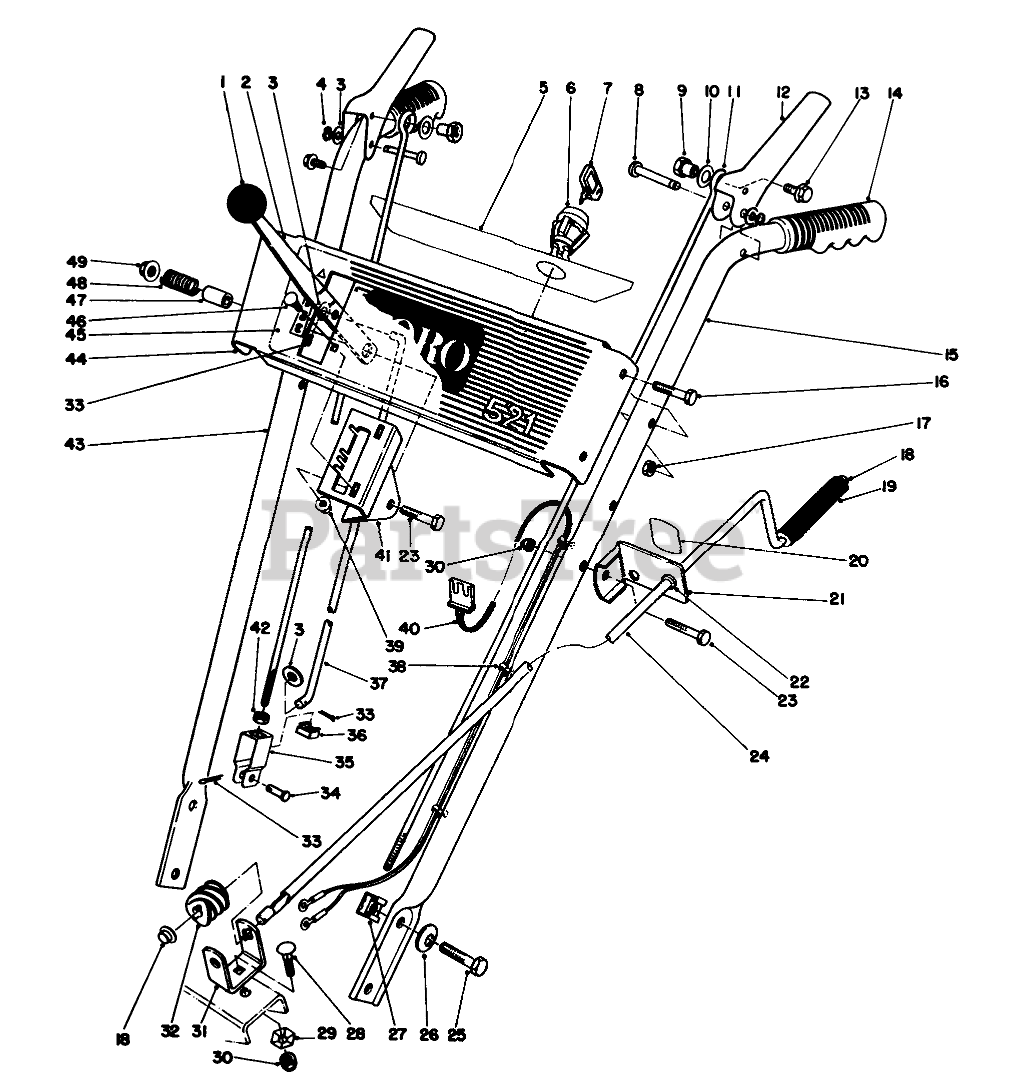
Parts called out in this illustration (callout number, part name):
2	SPEED SELECTOR B
3	WASHER-PLAIN
4	RING-CLIP
5	DECAL - ESCUTCHEON BACK
6	SWITCH
7	KEY-IGNITION
8	PIN-LEVER, CONTROL
9	POST-MOUNTING, LINKAGE
10	WASHER-FLAT
11	LINK-UPPER
12	HANDLE-CONTROL
13	SCREW-HHF
14	Grip
15	LEFT HANDLE
16	SCREW-HH
17	NUT-LOCK, NI
18	RETAINER-PUSH ON
19	Grip-Rod
20	DECAL-CHUTE DIRECTION
21	BRACKET W/DECAL
22	Bushing
23	SCREW-HH
24	ROD-CONTROL, CHUTE
25	SCREW-HH
26	WASHER-BELLEVILLE
28	BOLT-CARR
29	WASHER-LOCK
30	NUT-LOCK, NI
31	BRACKET-WORM
32	GEAR-WORM, CHUTE
33	PIN-COTTER
34	PIN-CLEVIS
35	CLEVIS
36	NUT-RETAINED
37	ROD-SELECTOR, SPEED
38	Mount-Wire
39	NUT-HF
40	WIRE HARNESS
41	Mount-Speed Selector
42	NUT-JAM
43	RIGHT HANDLE
44	ESCUTCHEON PLT B
45	DECAL ESCUTCHEON
46	SCREW-CARRIAGE
47	SPACER
48	SPRING
49	NUT-HF
